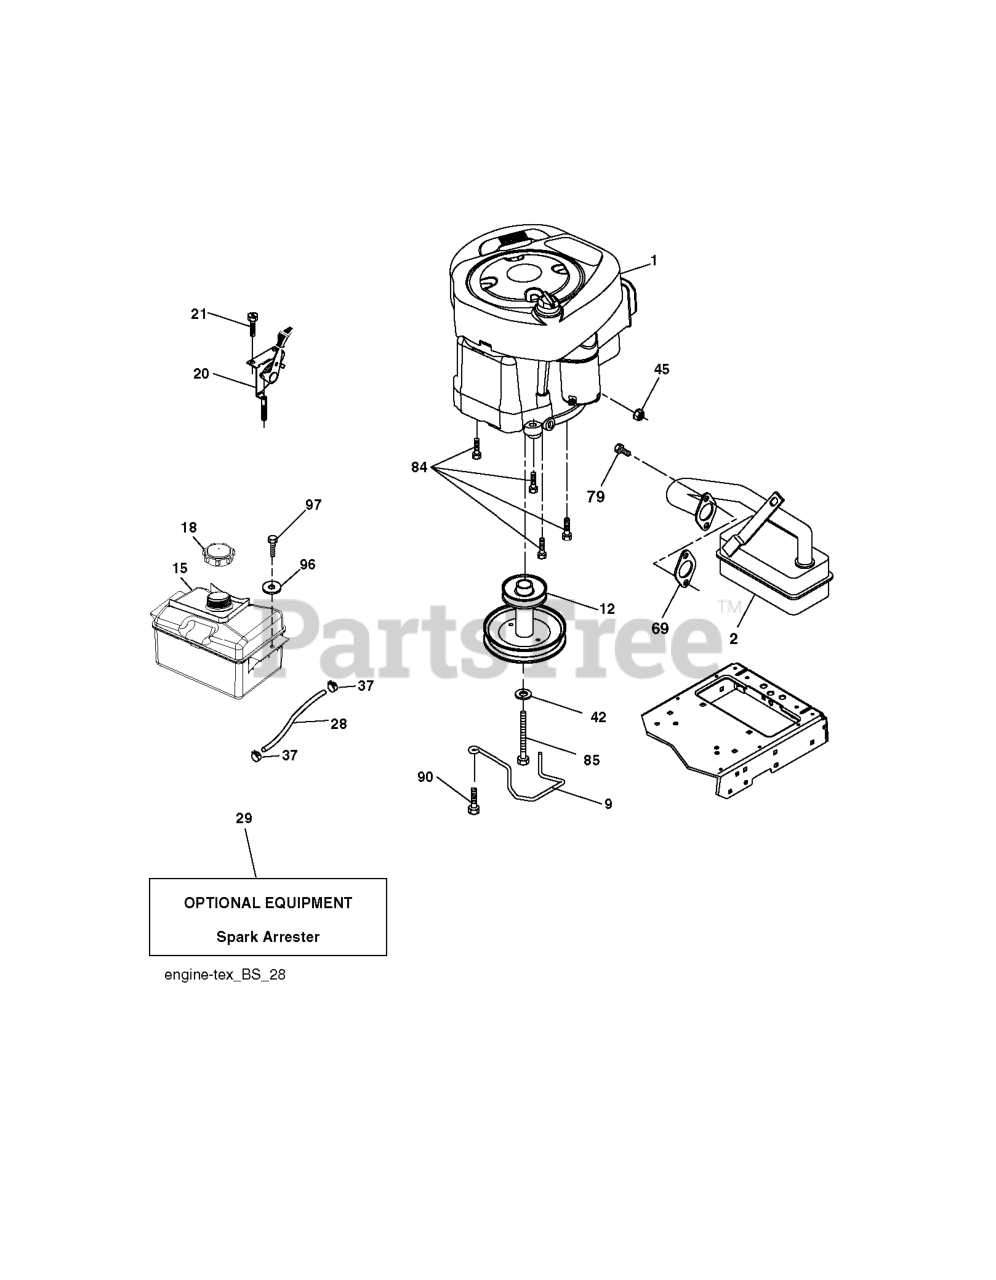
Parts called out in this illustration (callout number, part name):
2	MUFFLER.LT.BRIGGS.14HP.IC/OHV
9	KEEPER.BELT.ENGINE.3.25 (3 2)
12	PULLEY.ENG.CL.MECH.SLVR.LT/YT
15	RP TANK FUEL FRT 1.5 GAL
18	CAP ASM.FUEL.2.25"FR.
20	CONTROL.TH/CK.C.
21	SCREW.#10 X 0.750.BOS
28	LINE.FUEL.20
29	KIT.SPARK ARRESTOR 794945 B&S
37	HOSE CLAMP
42	LOCKWASHER
45	NUT
69	REPL BY 532 27 22-93
79	SCREW.SOCKET HD.5/16-1
84	SCREW.3/8-16
85	BOLT HEX 7/16-20X4-1/4"
90	SCREW 3/8-16X1
97	SCREW HEXWSHR 1/4-20X3/4
